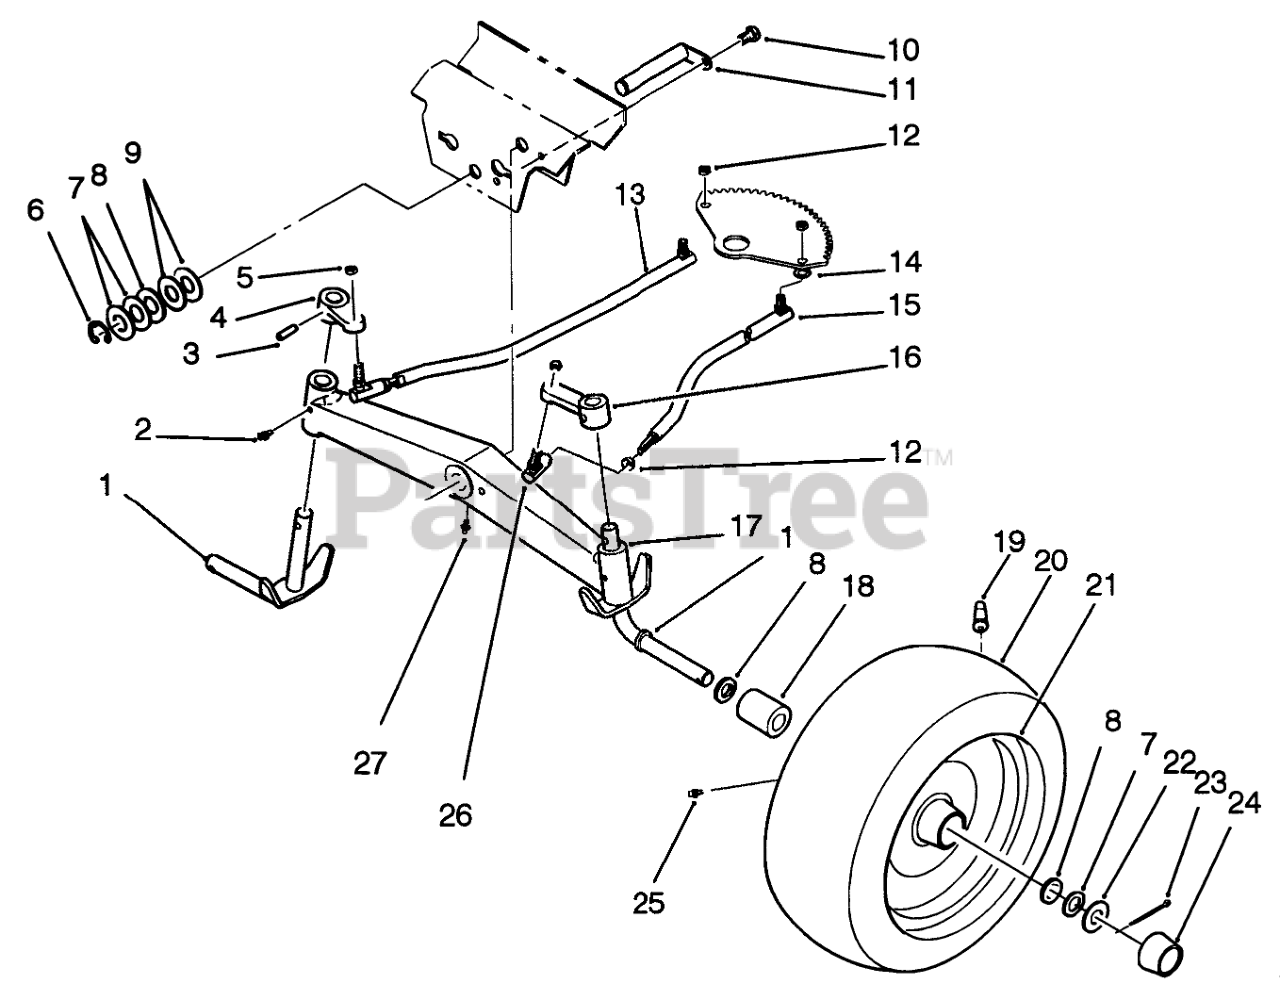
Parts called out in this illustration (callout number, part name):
1	Spindle
2	Fitting-Grease
4	Arm-Spindle, R.H.
5	Nut
6	E-RING
7	WASHER-SHIM
8	WASHER
9	WASHER
10	Bolt
11	WLDMT-AXLE PIN R
13	Ball Link ASM
14	WASHER-FLAT
15	Ball Link ASM
16	Arm-Spindle, L.H.
17	Axle-Front
18	BEARING-WHEEL
19	VALVE
20	Tire (16 x 6.5-8) 2-Ply -2 Wheel Axel
21	Wheel
22	WASHER WHEEL
23	PIN-COTTER
24	HUBCAP
25	ZERK-GREASE
26	BALL-JOINT
27	FITTING-GREASE
